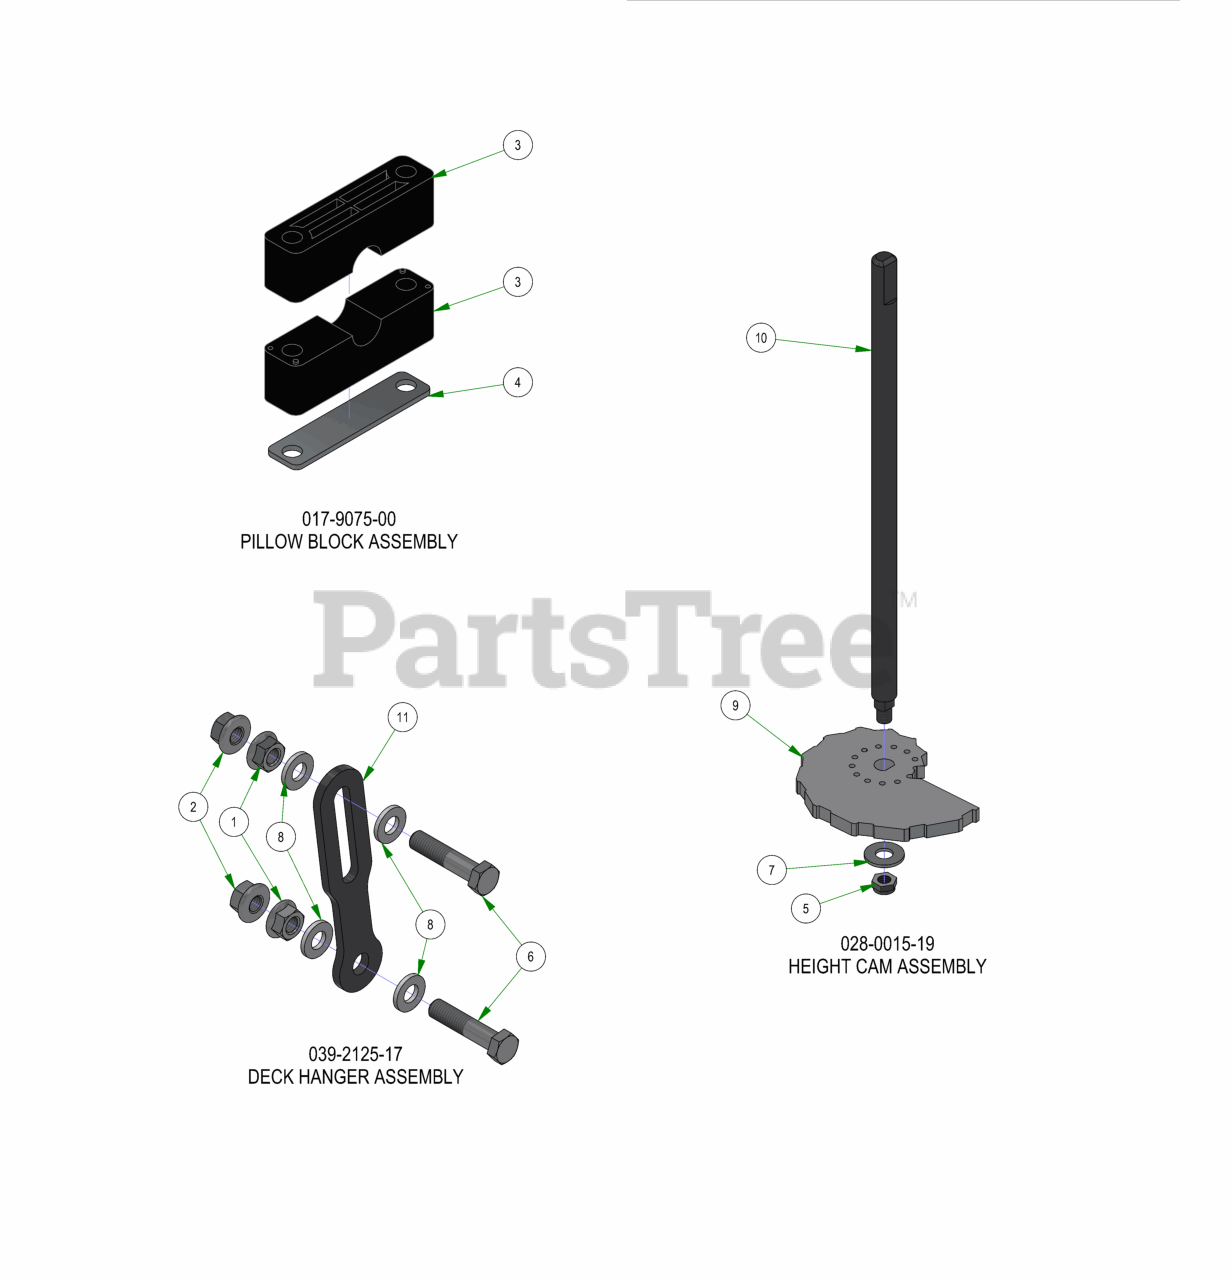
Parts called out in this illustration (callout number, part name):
1	1/2-13 HEX SERRATED FLANGE NUT HARD/ZINC
2	1/2-13 NYLON INSERT FLANGE LOCKNUT ZINC
3	Two Piece Pillow Block
4	Two Piece Pillow Block Strap
5	3/8-24 Nylon Insert jam locknut
6	1/2-13 X 2-1/4 HEX CAP SCREW (GR.5) ZINC
7	3/8 FLAT WASHER USS (1" OD) ZINC
8	.505 ID X 1.000 OD X .125 THICK FLAT WASHER NYLON
9	2019 Deck Height Cam
10	2019 Outlaw Gen2 Dial Rod
11	Deck Hanger
